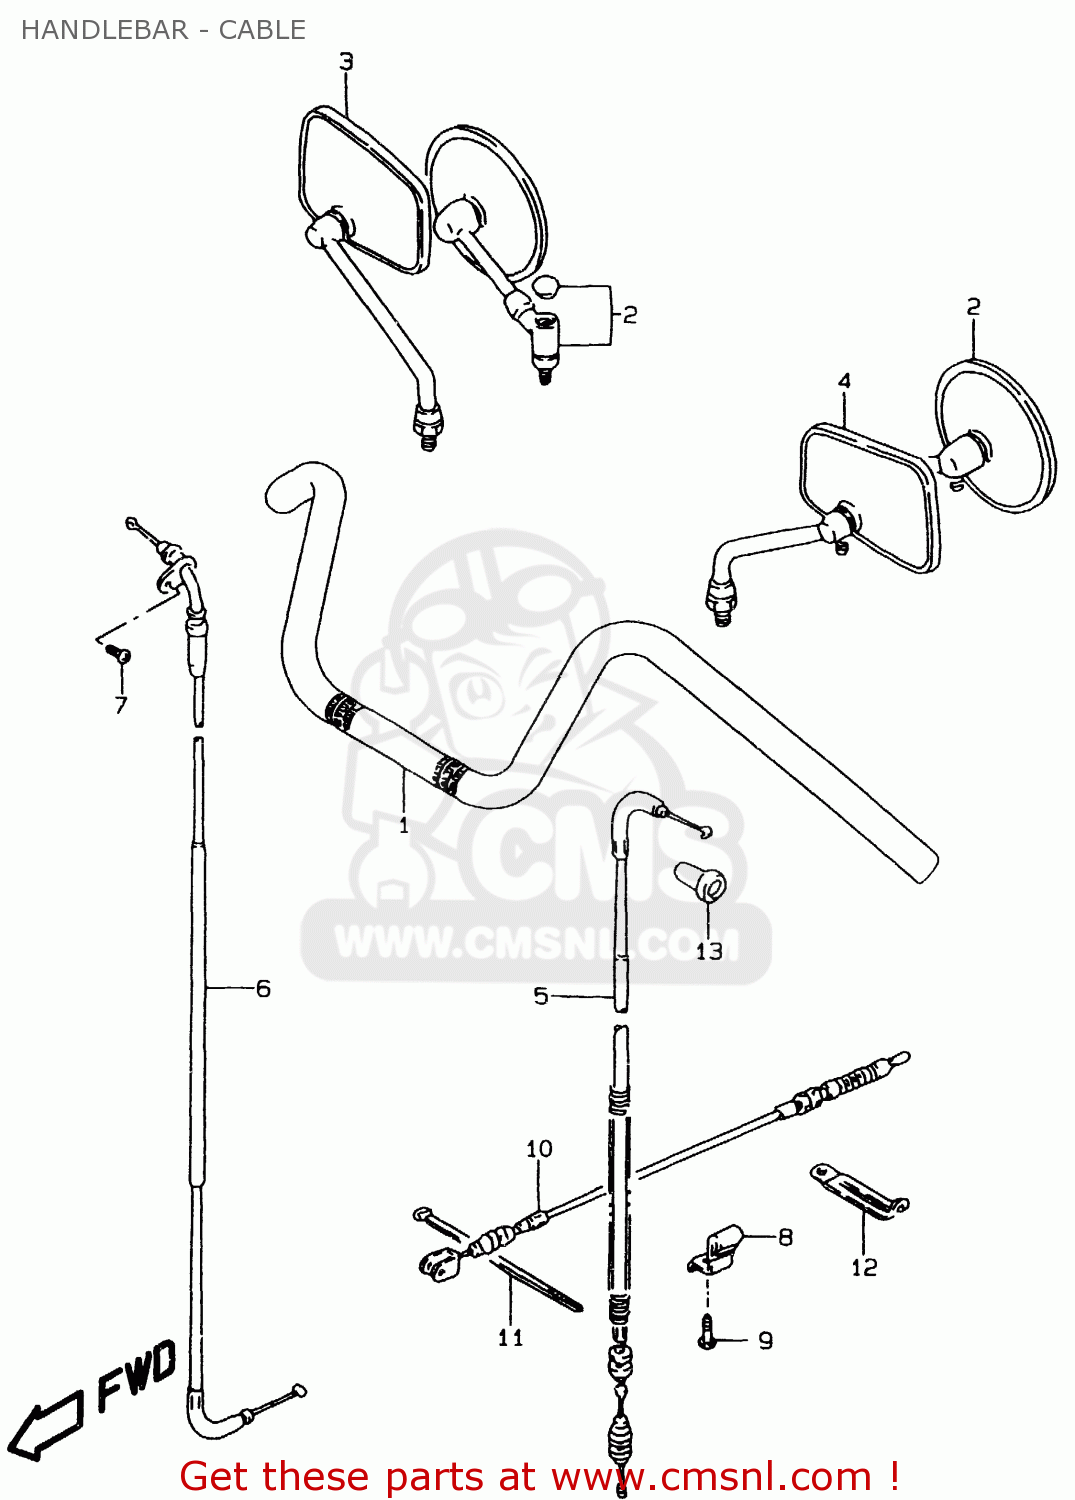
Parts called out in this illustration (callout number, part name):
1	HANDLEBAR
2	MIRROR ASSY,RH
3	MIRROR ASSY,RR VIEW,R
4	MIRROR ASSY,RR VIEW,L
5	CABLE ASSY,CLUTCH
6	CABLE ASSY,THROTTLE
7	SCREW
8	CLAMP,STOP LAMP SWITCH CABLE
9	BOLT
10	CABLE COMP,STOP LAMP SWITCH
11	CLAMP(L:65)
12	CLAMP(L:145)
13	BOOT,CLUTCH CABLE
